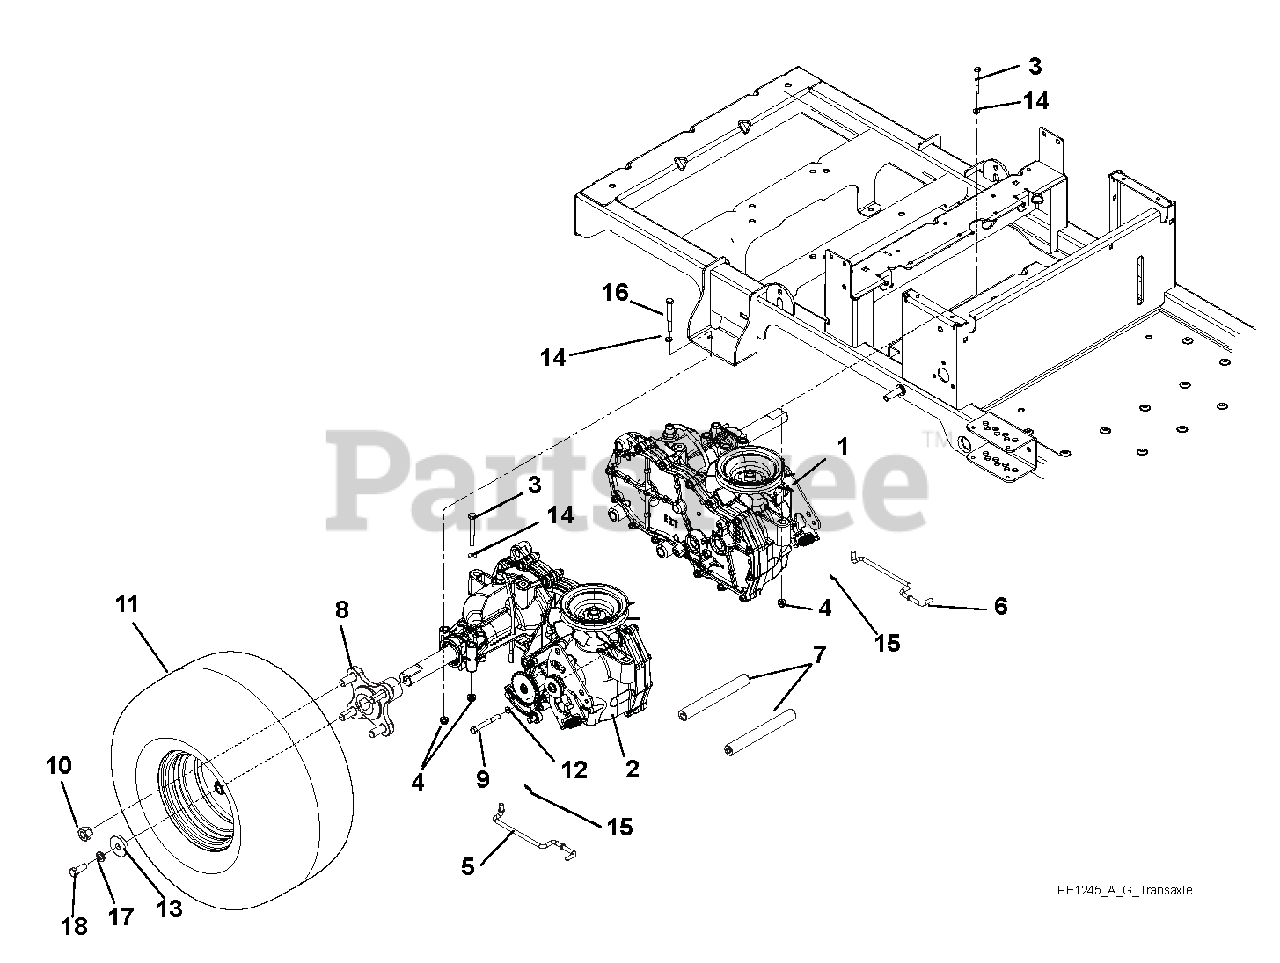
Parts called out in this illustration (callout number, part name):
1	TRANSAXLE, LH EZT D-SHAFT
2	TRANSAXLE, RH EZT D-SHAFT
3	@BLT-HEX .31-18X2.25 GR5 YWZC
4	@NUT-LK-NYL-FLG .31-18 YWZC
5	DUMPVALVE, RH LCZ
6	DUMPVALVE, LH LCZ
7	SHAFT, CROSS BRACE
8	ASM, WHEEL HUB
9	@BLT-HEX .38-16X2.50 GR5 YWZC
10	WHEEL NUT .500-20 YZ
11	TIRE-ASM 18X6.5-8 4 PLY DSHAFT
12	WSHR-FL-STL .406X1.00X.188 YWZ
13	WSHR,FLT STL.406X1.50X.245YWZC
14	@WSHR-FL-STL.38X.875X.083 YWZC
15	PIN-HAIR INT .06X.18X.77
16	@BLT-HEX .31-18X2.75 GR5 YWZC
17	@WSHR-LK .38X.094 REG YWZC
18	@BLT-HEX .38-16X1.00 GR5 YWZC
